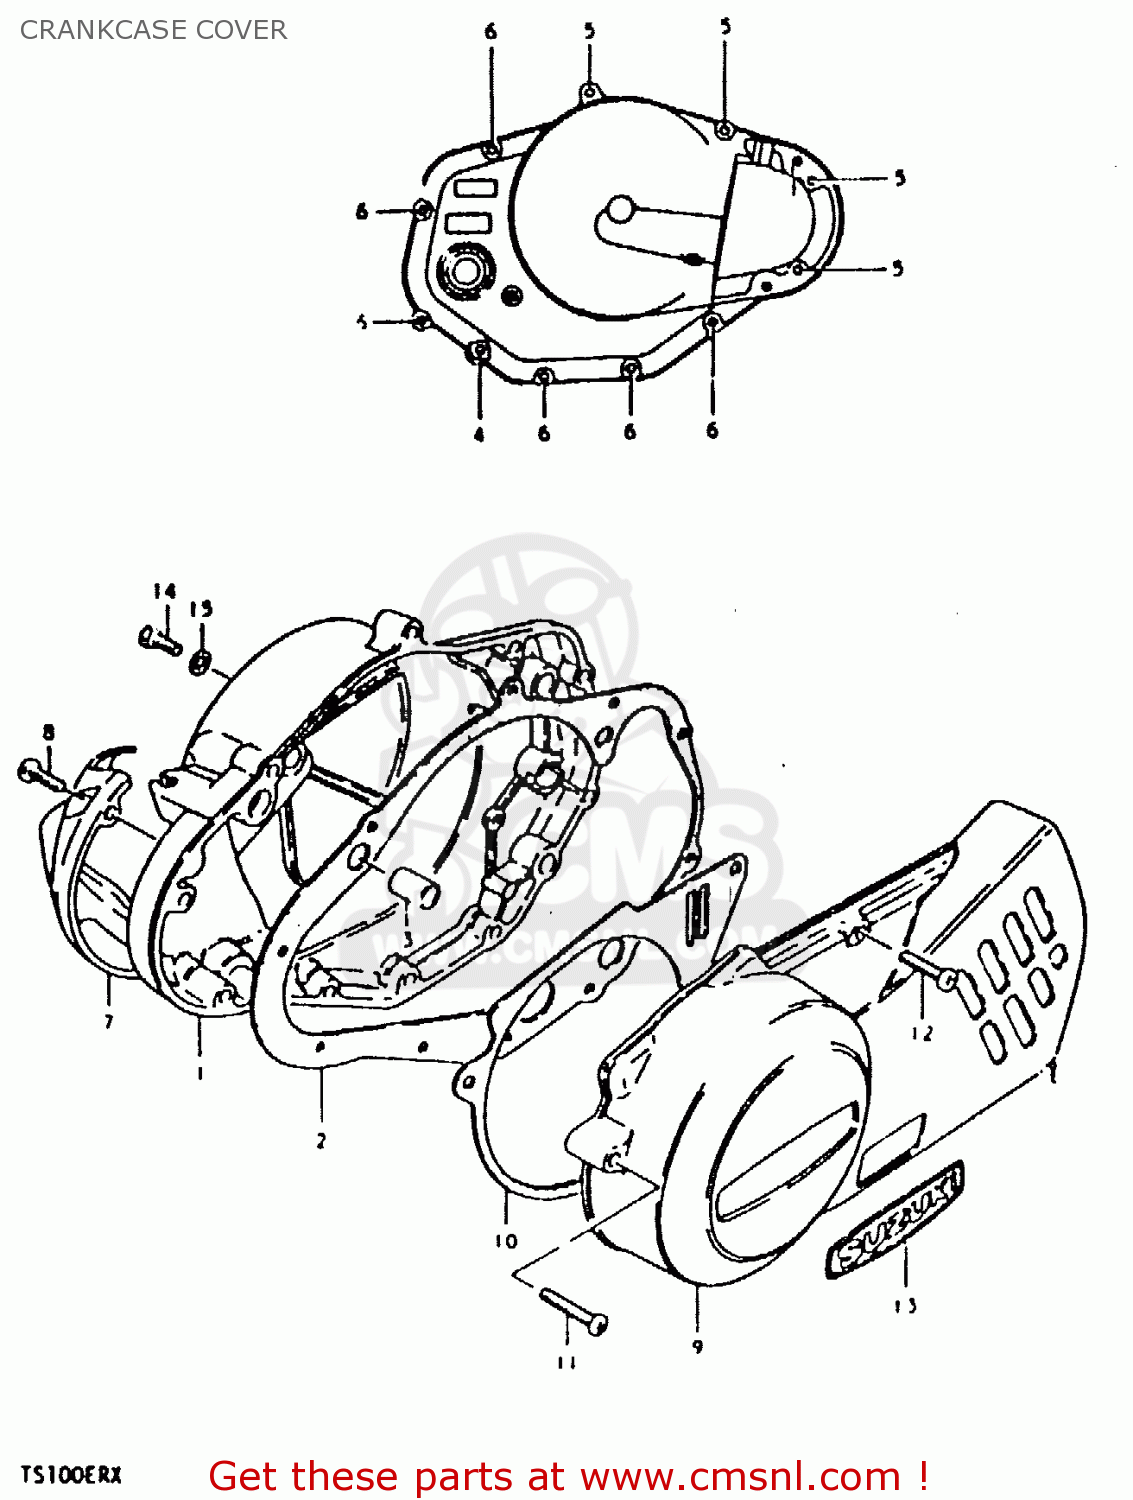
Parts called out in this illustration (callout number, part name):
1	COVER,CLUTCH
2	GASKET,CLUTCH COVER (MCA)
3	PIN
4	SCREW (6X45)
5	SCREW 6X30
6	SCREW
7	COVER,CLUTCH RELEASE ARM
8	SCREW
9	COVER,MAGNETO
10	GASKET,MAGNETO COVER (NAS)
11	SCREW 6X30
12	SCREW
13	EMBLEM,GENERATOR COVER
14	SCREW(6X10)
15	GASKET(6.2X11X1) (NAS)
